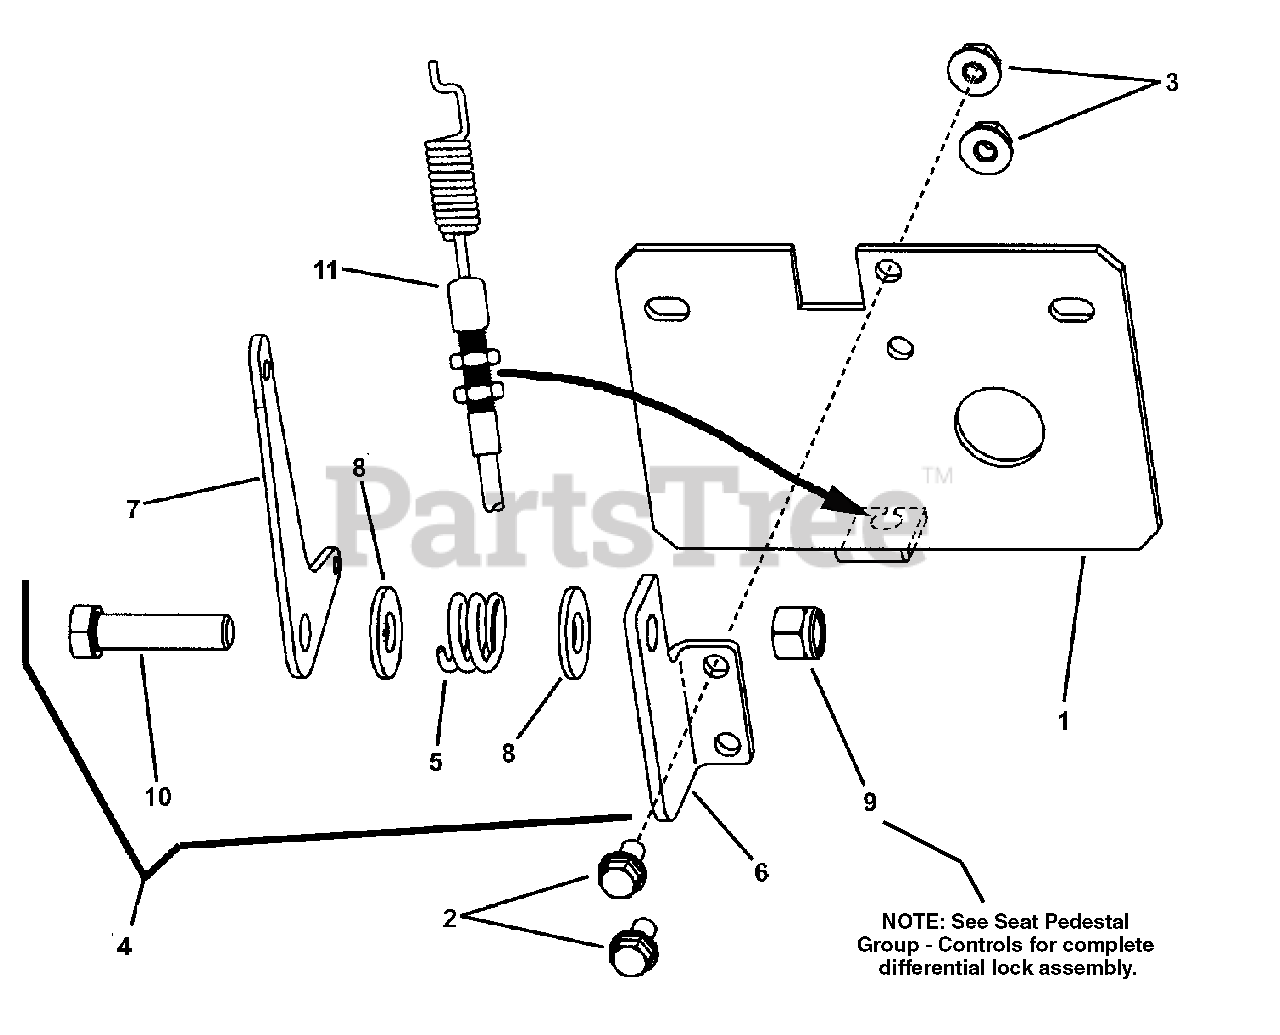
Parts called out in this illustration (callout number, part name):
1	PLATE, Differential Lock Mounting
2	SCREW, Hex Flange Lock, 1/4-20 x 1/2 GR 5
3	NUT, Hex Flange Lock, 1/4-20 GR 5
4	LOCK, Differential (Includes Ref. Nos. 5 thru 10)
5	SPRING, Friction Pack
6	BRACKET, Differential Lock
7	LEVER, Differential Lock
8	WASHER, 3/8 SAE Flat
9	NUT, Hex Nyloc, 3/8-16
10	CAPSCREW, Hex Washer Head, 3/8-16 x 1-1/2 GR 5
11	CABLE, Differential Lock
